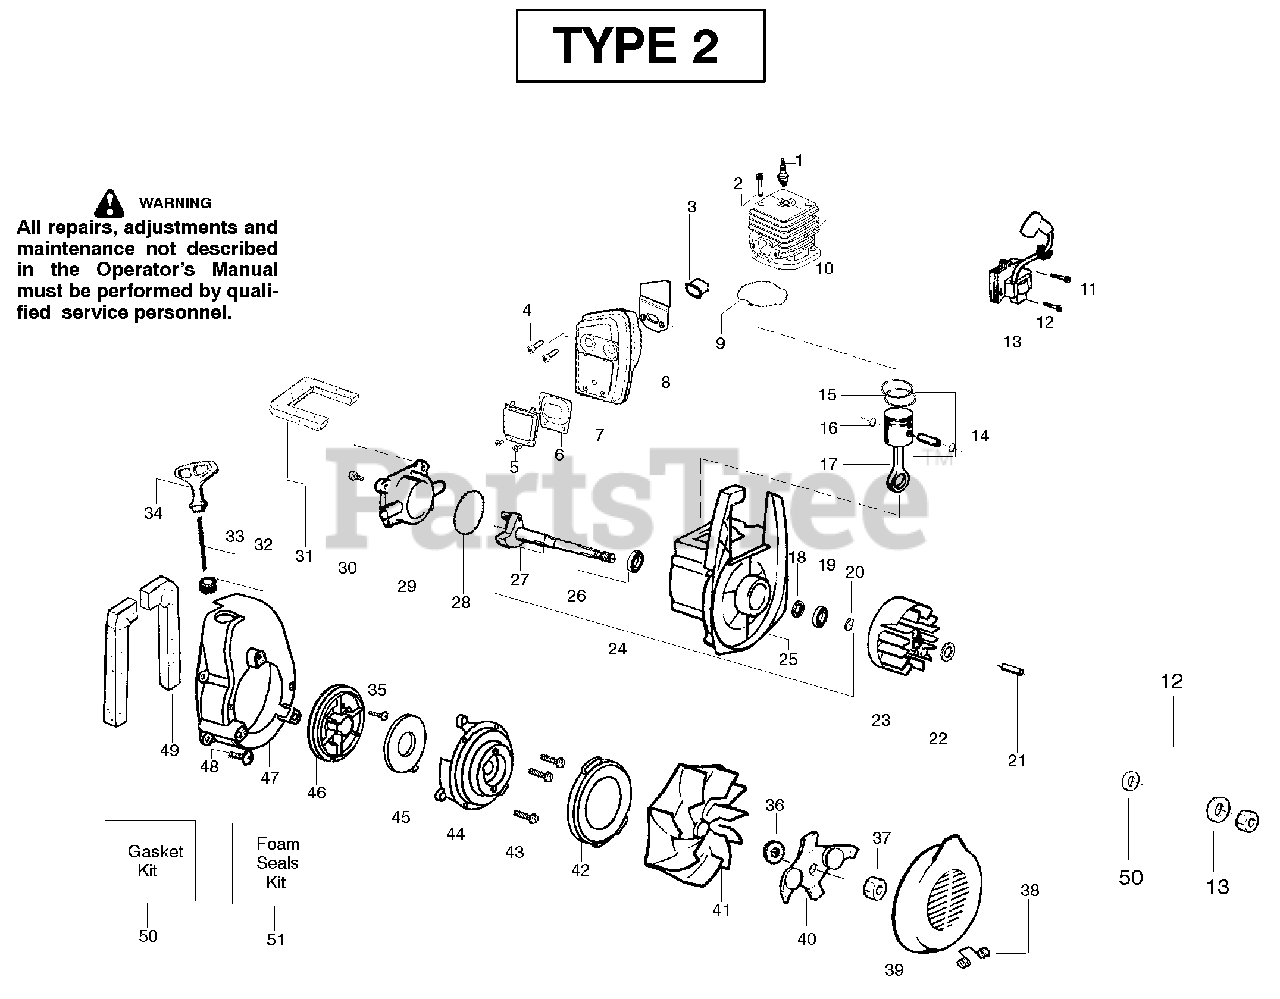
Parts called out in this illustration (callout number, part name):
1	Spark Plug (RCJ-6Y)
3	Insulator-Heat
4	Screw-Muffler-Internal
6	Kit-Spark Screen
7	Kit-Muffler
8	Gasket-Baffle (kit)
9	Gasket-Cylinder (kit)
10	Kit-Cylinder
11	Grommet-Ign. Module
12	Screw-Ignition Module
13	Ignition Module
14	Kit-Piston
15	Piston Ring
16	Retainer-Piston Pin
17	Assy-Connecting Rod
18	Kit-Crankcase Seal
19	Bearing-Outer
20	Retainer Ring-C'chaft
21	Spacer-Flywheel
23	Assy-Flywheel
24	Assy-Crankcase/Crank shaft
25	Assy-Crankcase
26	Bearing-Inner
27	Assy-Crankshaft
28	O-ring-C/case (kit)
29	Cover-Crankcase
30	Screw
31	Foam-219mm (kit)
32	Eyelet-Flange
33	Kit-Rope
34	Handle-Starter
35	Screw-Rope
36	Washer-Belleville
38	Spring-Return Cover
39	Inlet Door
40	Assy-Mulch Blade
41	Assy-Impeller
42	Seal-Ring
44	Housing-Pulley
45	Spring-Starter
46	Kit-Starter Pulley
47	Fan Housing
48	Screw
49	Foam-182mm (kit)
50	Kit-Gasket
51	Kit-Foam Seals
